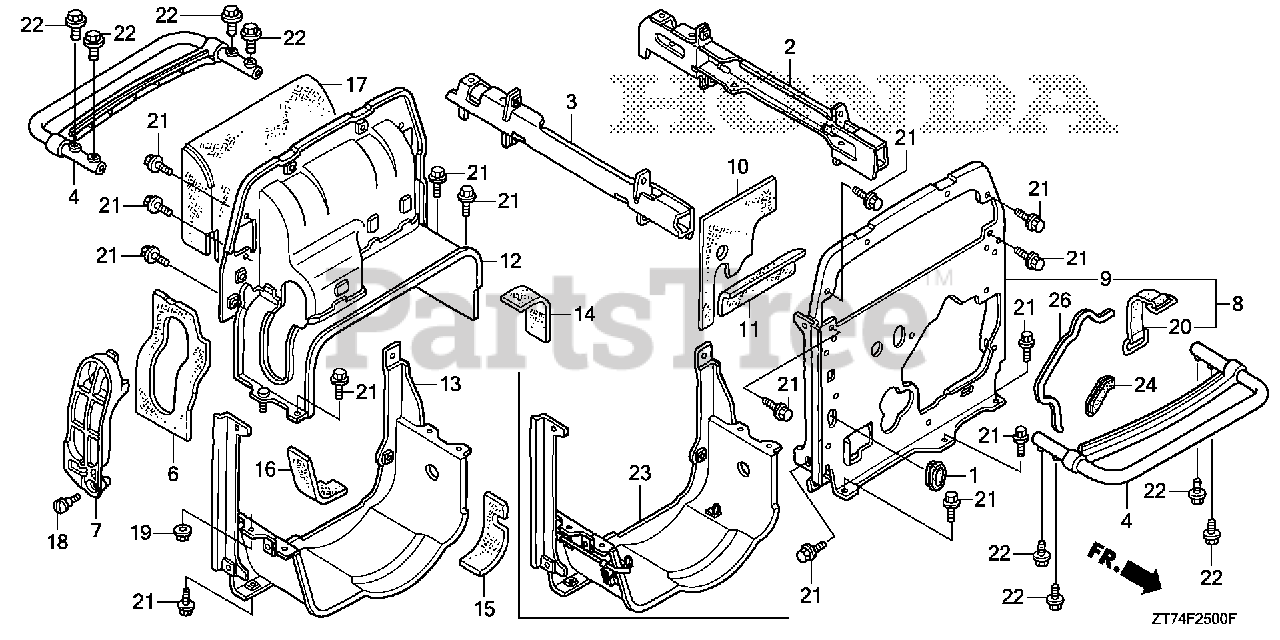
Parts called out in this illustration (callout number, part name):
1	GROMMET, FUEL TUBE
2	STAY, TANK
3	STAY, TANK
4	PIPE, HANDLE *NH314* (CONDUCT GRAY)
6	SEAL, MAINTENANCE COVER PLUG
7	COVER, PLUG CHECK
8	FRAME ASSY., FR.
9	FRAME, FR.
10	INSULATOR A, FR. FRAME
11	INSULATOR B, FR. FRAME
12	FRAME, RR. (UPPER)
14	INSULATOR A, RR. FRAME
15	INSULATOR B, RR. FRAME
16	INSULATOR C, RR. FRAME
17	INSULATOR A, HEAT PROTECTOR
18	SCREW, SPECIAL (6X16)
19	NUT, FLANGE (6MM)
20	BAND F, BATTERY (155MM)
21	BOLT, FLANGE (6X10)
22	BOLT, FLANGE (8X20)
23	FRAME, RR. (LOWER)
25	RUBBER, PROTECTOR
26	RUBBER, PROTECTOR
